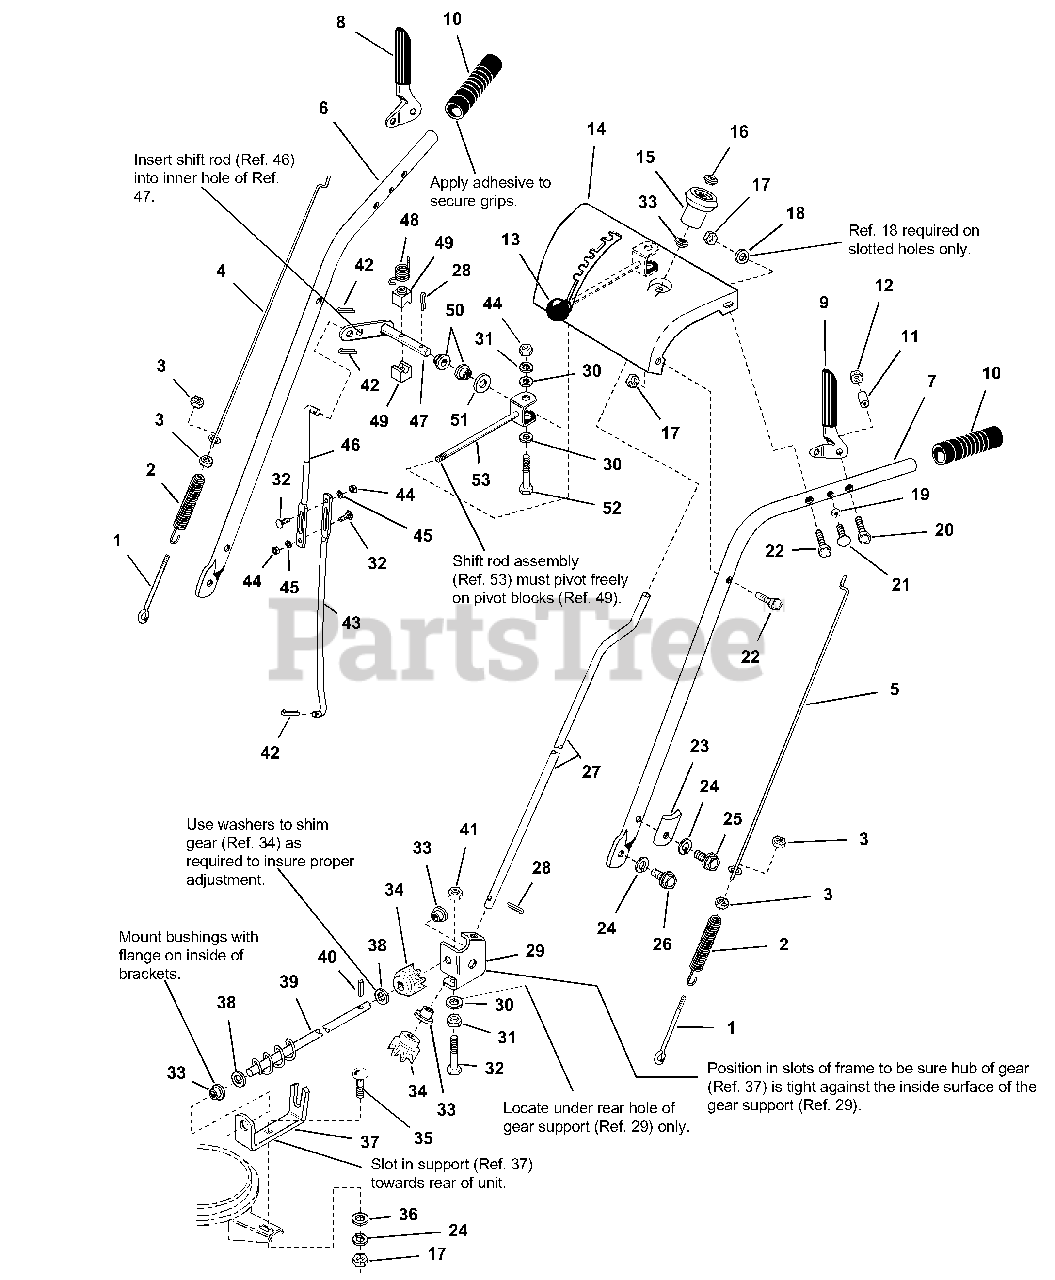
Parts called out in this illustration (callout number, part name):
1	ROD, Control, Lower
2	SPRING, Extension
3	NUT, Hex, #10-24 R.H.
4	CLUTCH ROD, Traction Drive
5	CLUTCH ROD, Auger Drive
6	HANDLE, R.H.
7	HANDLE, L.H.
8	LEVER, Auger Clutch, R.H.
9	LEVER, Traction Drive Clutch, L.H.
10	GRIP, Black Vinyl, for 1" Tube
11	SPACER, Large
12	NUT, Hex, Centerlock, 1/4-20
13	KNOB, Int. thrd., 3/8-16
14	DASHBOARD & SUPPORT ASMY
15	KNOB, Chute Control Spinner
16	NUT, Push, 3/8
17	NUT, Hex Lock, 5/16-18
18	WASHER, Flat 5/16
19	SPACER, Small
20	CAPSCREW, Hex Hd., 1/4-20 x 1-1/2
21	SCREW, Taptite, Pan Hd., Torx, 1/4-20 x 3/4
22	CAPSCREW, Hex Hd. 5/16-18 x 1-1/2
23	CLAMP, Tube, Saddle
24	LOCKWASHER, 5/16
25	CAPSCREW, Hex Hd. 5/16-18 x 1 3/4
26	CAPSCREW, Hex Hd. 5/16-18 x 3/4
27	ROD, Chute Control
28	PIN, Cotter
29	SUPPORT, Gear
30	WASHER, Flat 1/4
31	NUT, Push
32	BOLT, Rd. Hd., 1/4-20 X 3/4
33	BUSHING, Nylon
34	GEAR, Steel, Universal
35	CARRIAGE BOLT, 5/16-18 X 3/4
36	WASHER, Flat 5/16
37	BRACKET, Worm Support
38	WASHER, Flat 3/8
39	WORM ASSEMBLY
40	PIN, Spring
41	NUT, Hex, Fl., 1/4-20
42	PIN, Cotter
43	ROD, Shift, Lower
44	NUT, Hex Hd., 1/4-20
45	LOCKWASHER
46	ROD, Shift, Upper
47	ROD & ARM ASMY, Pivot
48	SPRING, Torsion
49	BLOCK, Pivot
51	WASHER
52	CAPSCREW, Hex Hd., 1/4-20 x 2-1/4
53	ROD & CLEVIS ASSY.
